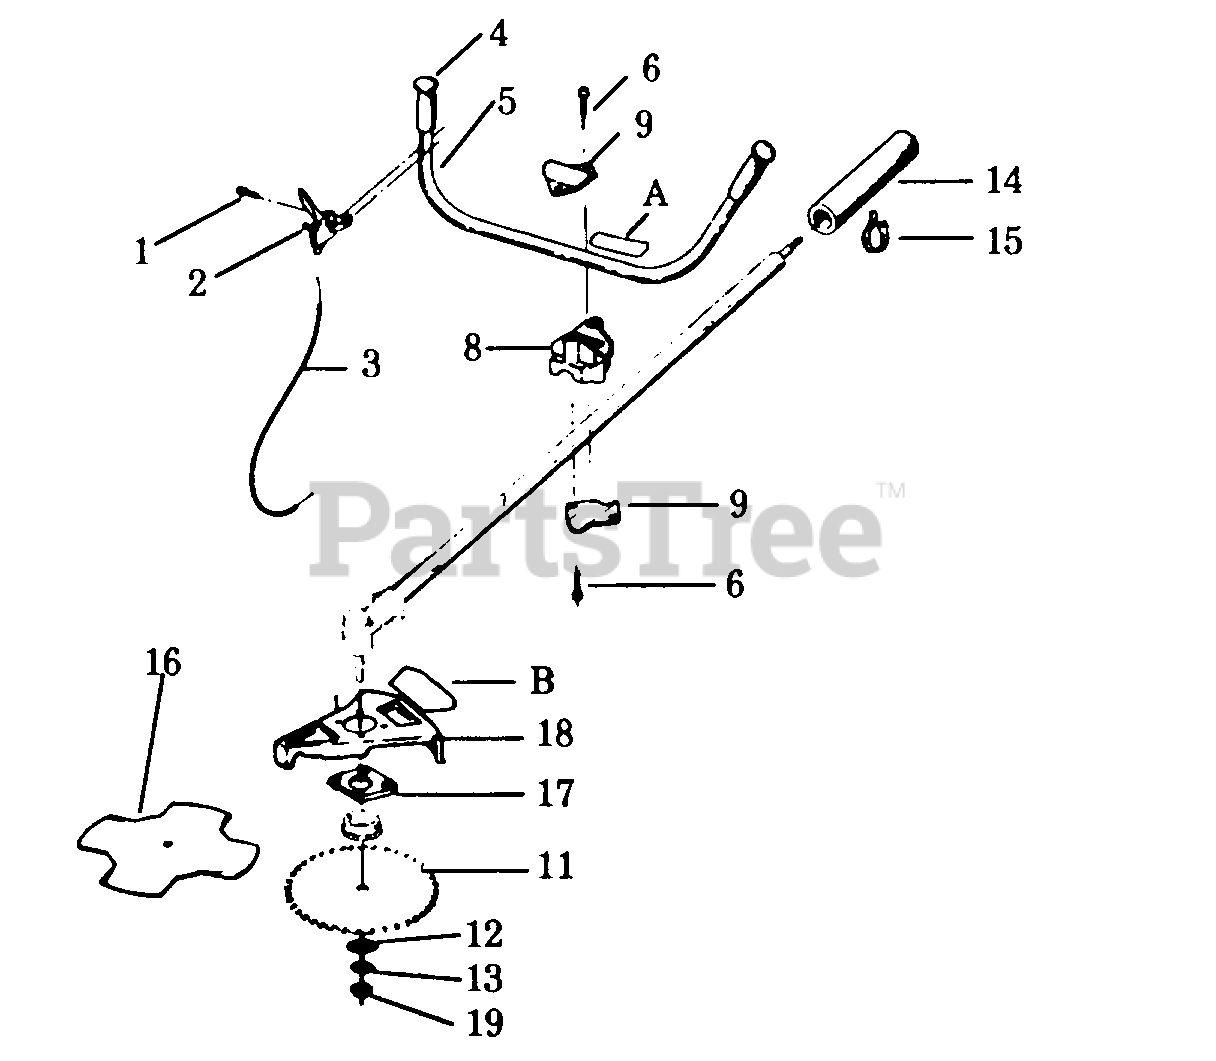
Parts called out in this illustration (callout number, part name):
2	Throttle Control Ass'y.
3	Throttle Cable
4	Handlebar Grip
5	Handlebar
8	Handlebar Clamp
9	Handlebar Bracket
11	XR-125
13	Washer
14	Drive Shaft Pad
15	Tie Strap
16	XR-105 (Optional for this Model)
16	XR-125
17	Shield Retention Plate
18	Shield
A	Handlebar Warning Decal
B	Blade Rotation Decal (Not a serviceable part)
